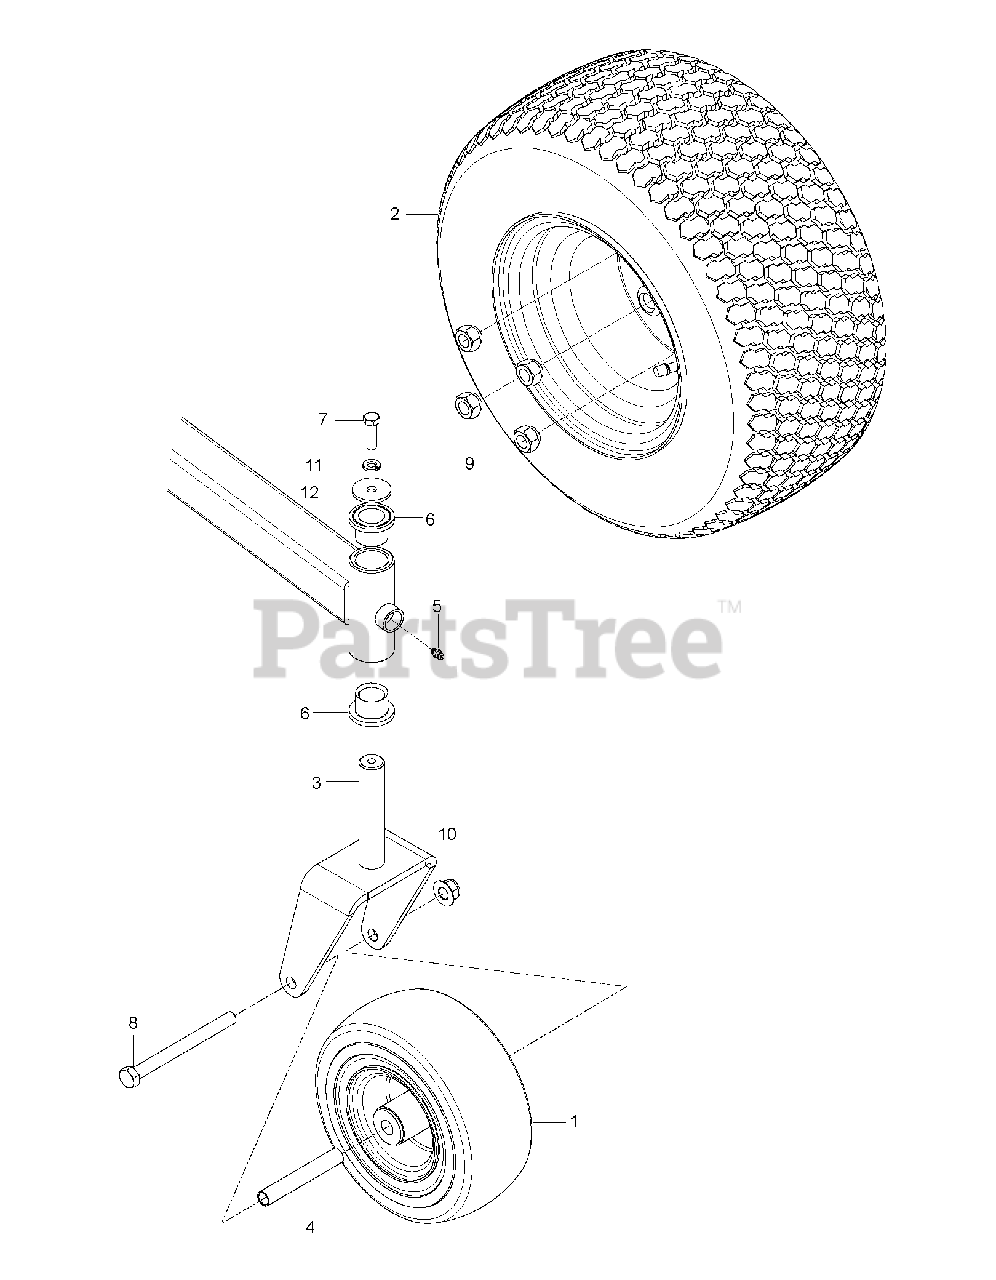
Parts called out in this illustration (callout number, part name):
1	WHEEL ASSY WHEEL & TIRE 9X3.5
2	WHEEL ASSY WHL/TIRE 16X7.50-8
3	FLOAT WLDMT FRONT WHEEL FLOAT
4	TUBE TUBE, CASTER AXLE
5	FITTING FITTING, 1/4-28 STRGT
6	BEARING BRG, FLG 1.00 X 1.25 X
7	BOLT BOLT 3/8-16X1-1/4 HEX HEA
8	BOLT BOLT HEX .50-13 X 5.50 G
9	SERVICE PARTS SYSTEM WHEEL NUT
10	NUT NUT, LK-NYL-FLG .50-13 YWZ
11	WASHER WASHER, LK .38 X .094 R
12	SERVICE PARTS SYSTEM WASHER, F
